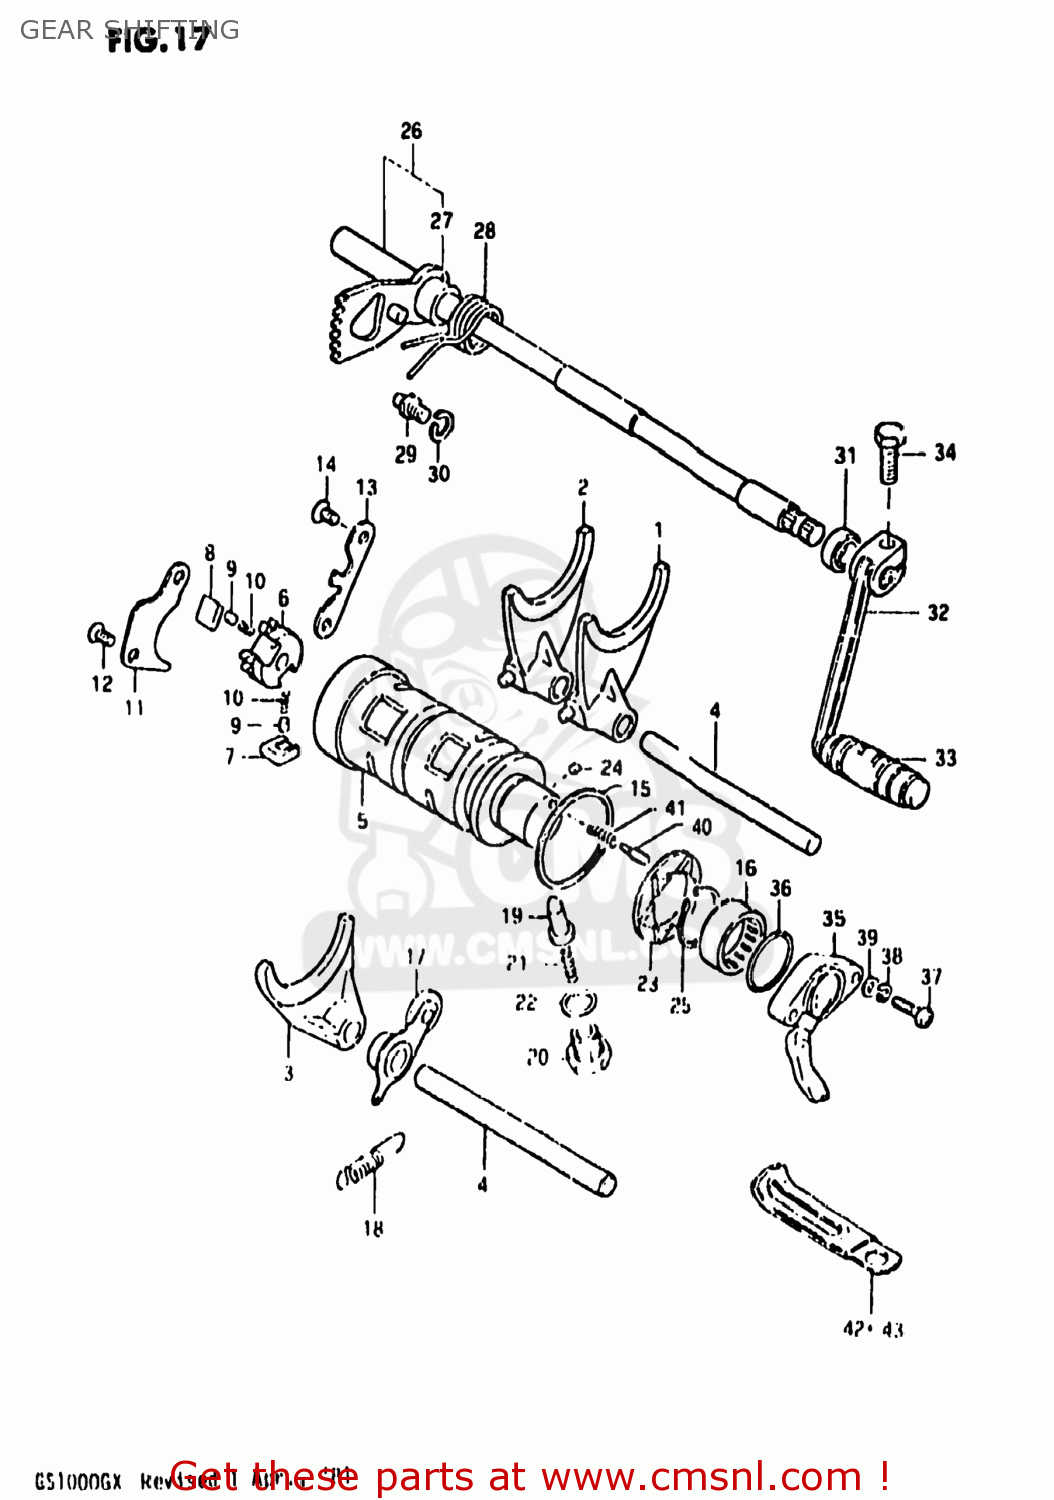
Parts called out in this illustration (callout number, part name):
1	FORK,GEAR SHIFT NO.1
2	FORK,GEAR SHIFT NO.1
3	FORK,GEAR SHIFT NO.3
4	SHAFT,GEAR SHIFT FORK
5	CAM,GEAR SHIFT
6	RETAINER,GEAR SHIFT CAM
7	PAWL,GEAR SHIFT NO.1
8	PAWL,GEAR SHIFT NO.2
9	PIN(5X8)
10	SPRING
11	LIFTER,GEAR SHIFT PAWL
12	SCREW
13	GUIDE,GEAR SHIFT CAM
14	SCREW
15	WASHER(40X45X1)
16	BEARING(25X32X12)
17	STOPPER,GEAR SHIFTING
18	SPRING
19	STOPPER,GEAR SHIFT CAM NO.2
20	HOLDER,GEAR SHIFT CAM STOP SPR
21	SPRING
22	GASKET(14X19.2X2) (NAS)
23	PLATE,GEAR SHIFT CAM STOPPER
24	PIN 4X6
25	CIRCLIP
26	SHAFT,GEAR SHIFT
27	SPACER (12X20X12)
28	SPRING
29	STOPPER,GEAR SHIFT CAM
30	WASHER
31	OIL SEAL
32	LEVER ASSEMBLY,GEAR SHIFTING
33	RUBBER,GEAR SHIFT PEDAL
34	BOLT
35	TERMINAL BASE ASSY,GEAR SHIFT
36	O-RING (D:2.4 ID:26.2)
37	SCREW 5X20
38	LOCK WASHER
39	WASHER
40	PIN(5X15.5)
41	SPRING
42	CLAMP L:35
43	CLAMP
